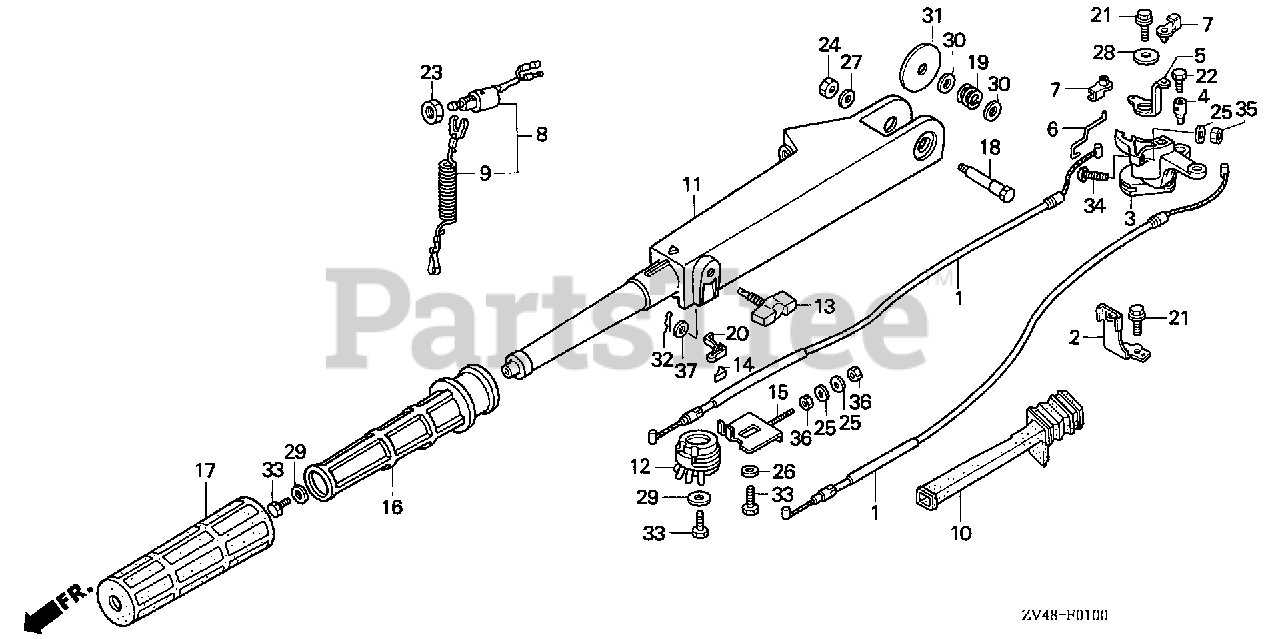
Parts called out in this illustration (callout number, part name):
1	CABLE, THROTTLE
2	CLAMP, THROTTLE CABLE
3	ARM, THROTTLE
4	HOLDER, THROTTLE ROD
5	ARM, CHOKE
6	ROD, CHOKE KNOB
7	BUSH, LINKAGE
8	SWITCH ASSY., EMERGENCY STOP
9	WIRE, EMERGENCY
10	GROMMET, OIL CASE (A)
11	HANDLEBAR *NH282MU* (OYSTER SILVER METALLIC-U)
12	REEL, CABLE
13	BOLT, FRICTION
14	BLOCK, THROTTLE FRICTION
15	PLATE, ADJUSTING
16	PIPE, GRIP
17	RUBBER, GRIP
18	SCREW, HANDLE PIVOT
19	SPRING, HANDLE PIVOT
20	SPRING, THROTTLE FRICTION
21	BOLT, FLANGE (6X12)
22	BOLT, RECESSED (5X8)
23	NUT, HEX. (16MM)
24	NUT, HEX. (8MM)
25	WASHER, PLAIN (5MM)
26	WASHER, PLAIN (6MM)
27	WASHER, PLAIN (8MM)
28	WASHER, PLAIN (6MM)
29	WASHER (6MM)
30	WASHER (10MM)
31	WASHER, HANDLEBAR
32	PIN, SPLIT (2.0)
33	BOLT, HEX. (6X12)
34	SCREW, PAN (5X40)
35	NUT, HEX. (5MM)
36	NUT, HEX. (5MM)
37	WASHER, PLAIN (4MM)
